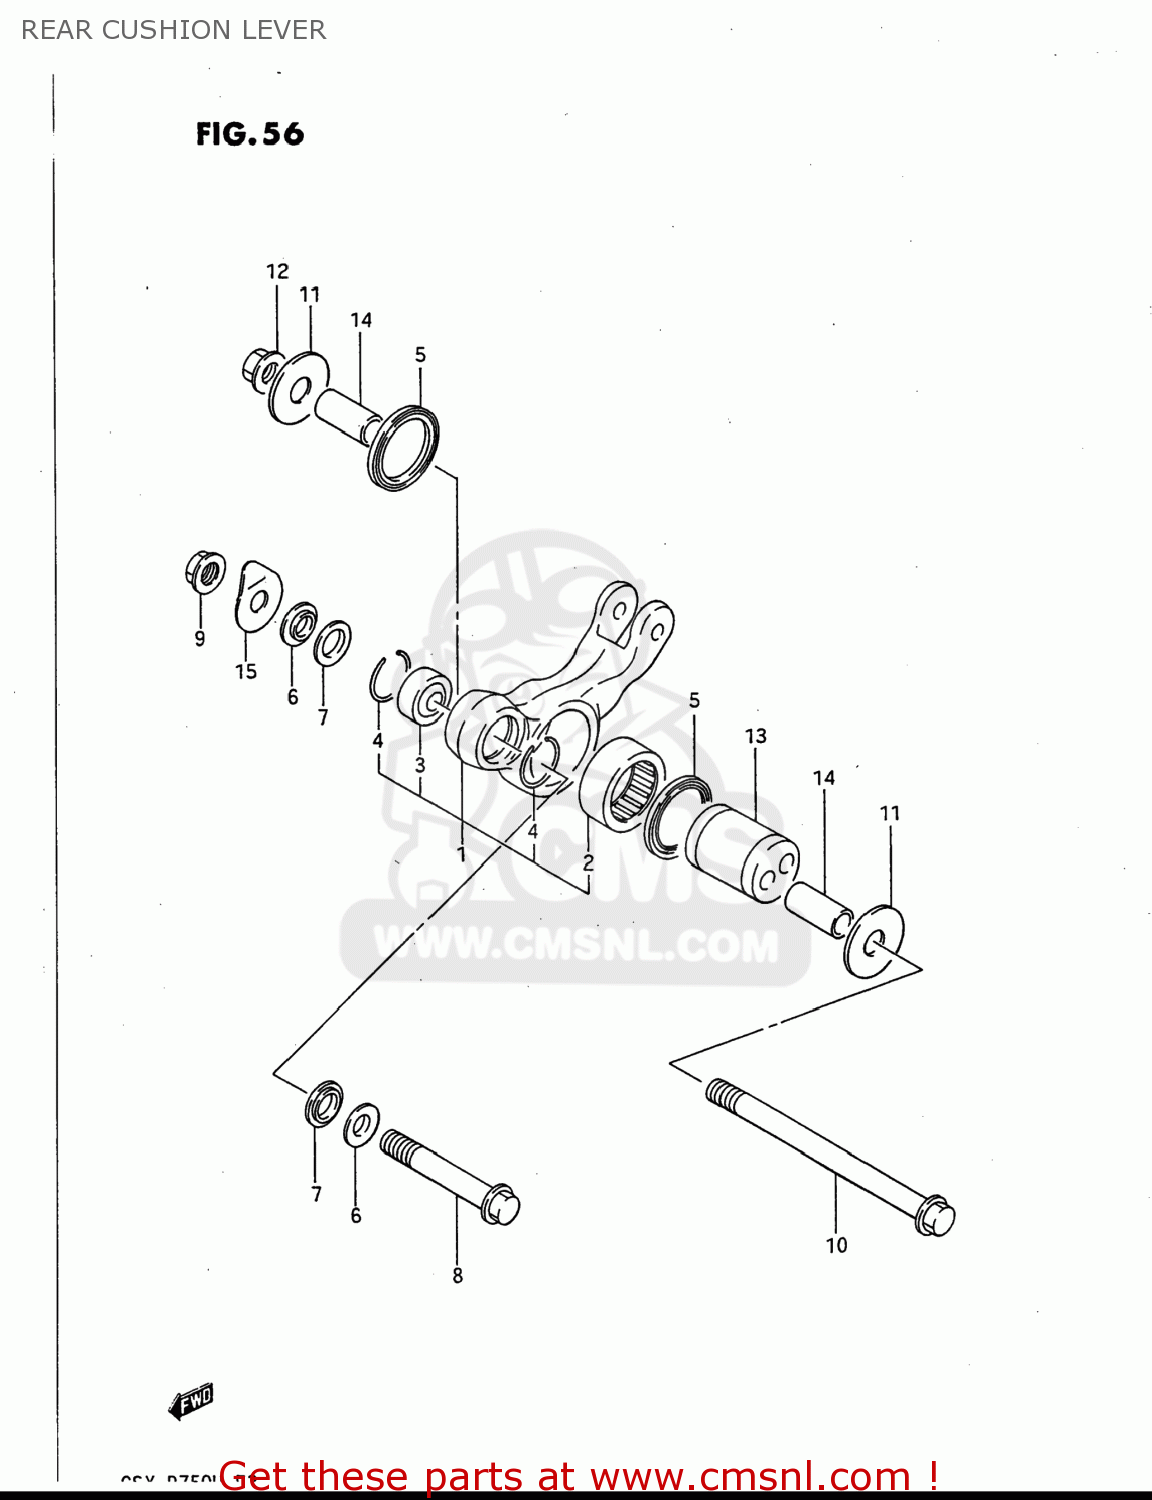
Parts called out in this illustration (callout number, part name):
1	LEVER SET,REAR CUSHION
2	BEARING(35X45X20)
3	BEARING(12X26X16)
4	RING,STOPPER
5	SEAL,INNER DUST
6	SPACER,RR CUSHION ROD
7	SEAL,RR CUSHION ROD DUST
8	BOLT,RR CUSHION LEVER FR
9	NUT 12MM
10	SHAFT
11	WASHER(12X40X2.5)
12	NUT 12MM
13	SPACER,REAR CUSHION ECCENTRIC
14	SPACER
15	SHIM,REAR CUSHION LEVER
